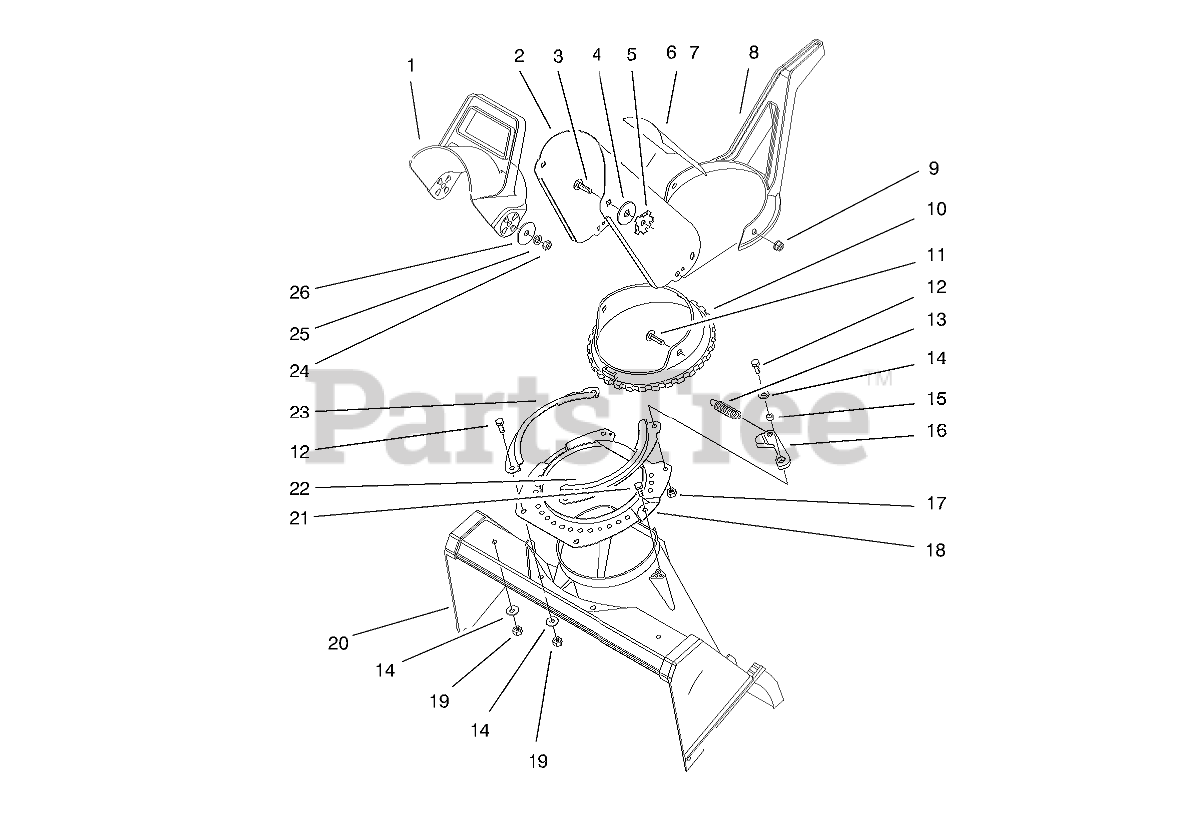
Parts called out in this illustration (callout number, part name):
1	CHUTE-DEFLECTOR
2	Chute-Discharge
2	CHUTE ASM W/DECAL
2	CHUTE ASM
3	SCREW-CARR
4	WASHER-RUBBER
5	PLATE-FRICTION
6	DECAL - DANGER DISCHARGE
7	DECAL-DANGER
8	HANDLE-CONTROL, CHUTE
9	NUT-KEPS
10	GEAR RING, CHUTE
11	SCREW-CARR
12	SCREW-HH
13	SPRING-EXTENSION
14	WASHER-FLAT
15	SPACER-BLADE, ROTOR
16	DETENT
17	NUT-LOCK, NI
18	Ring-Chute Support
19	NUT-LOCK, NI
20	HOUSING
21	SCREW-PLASTITE
22	LH CHUTE RING RETR RED
23	Retainer-Chute Ring
24	NUT-LOCK, NI
25	WASHER-BELLEVILLE
26	WASHER-FLAT
